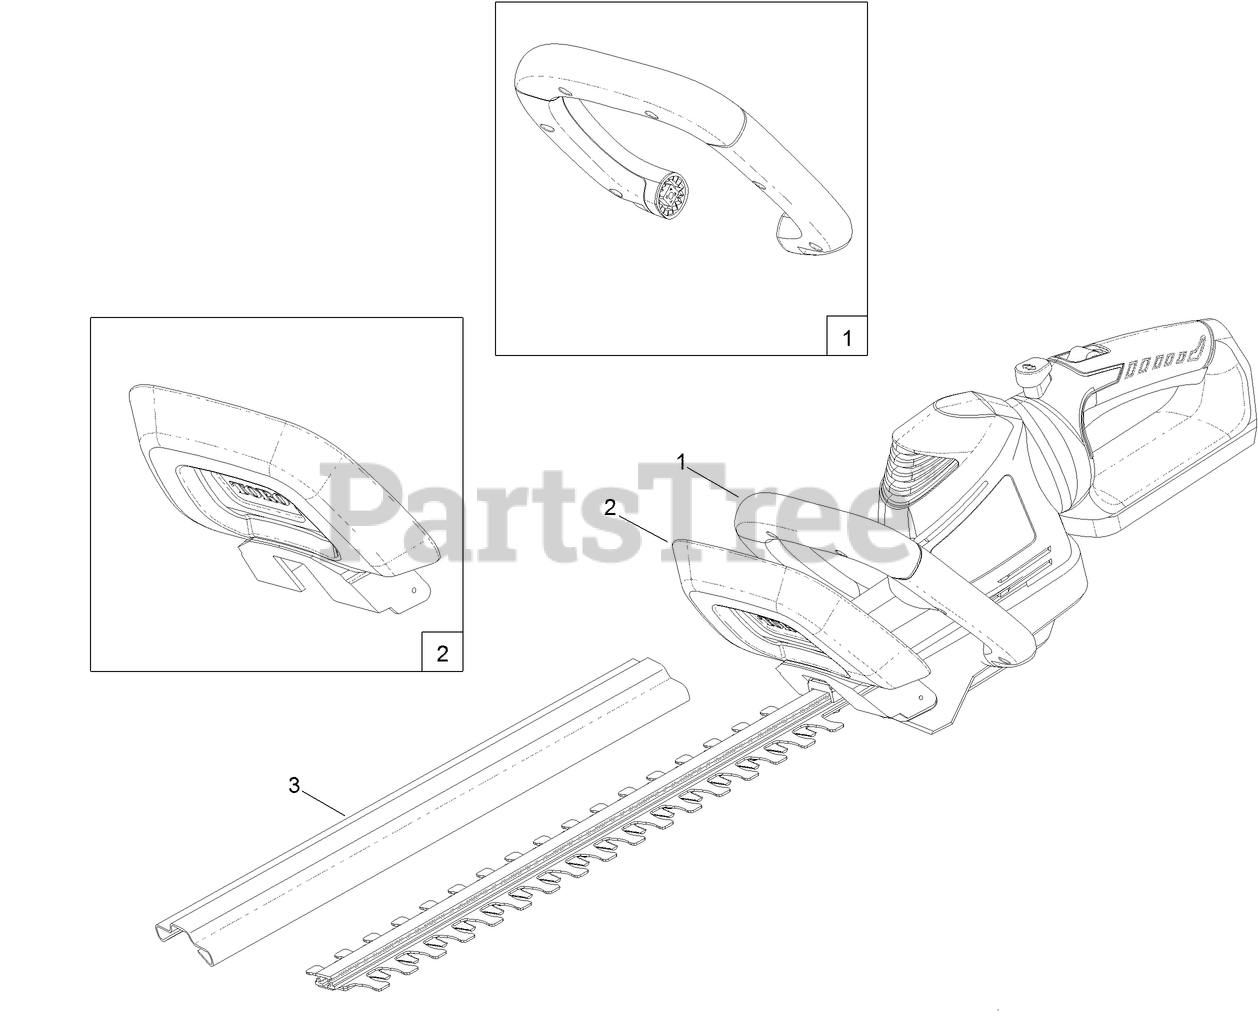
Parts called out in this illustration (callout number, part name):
1	HANDLE-ASSIST
2	GUARD-TRIMMER, HEDGE
3	GUARD-TRIMMER
